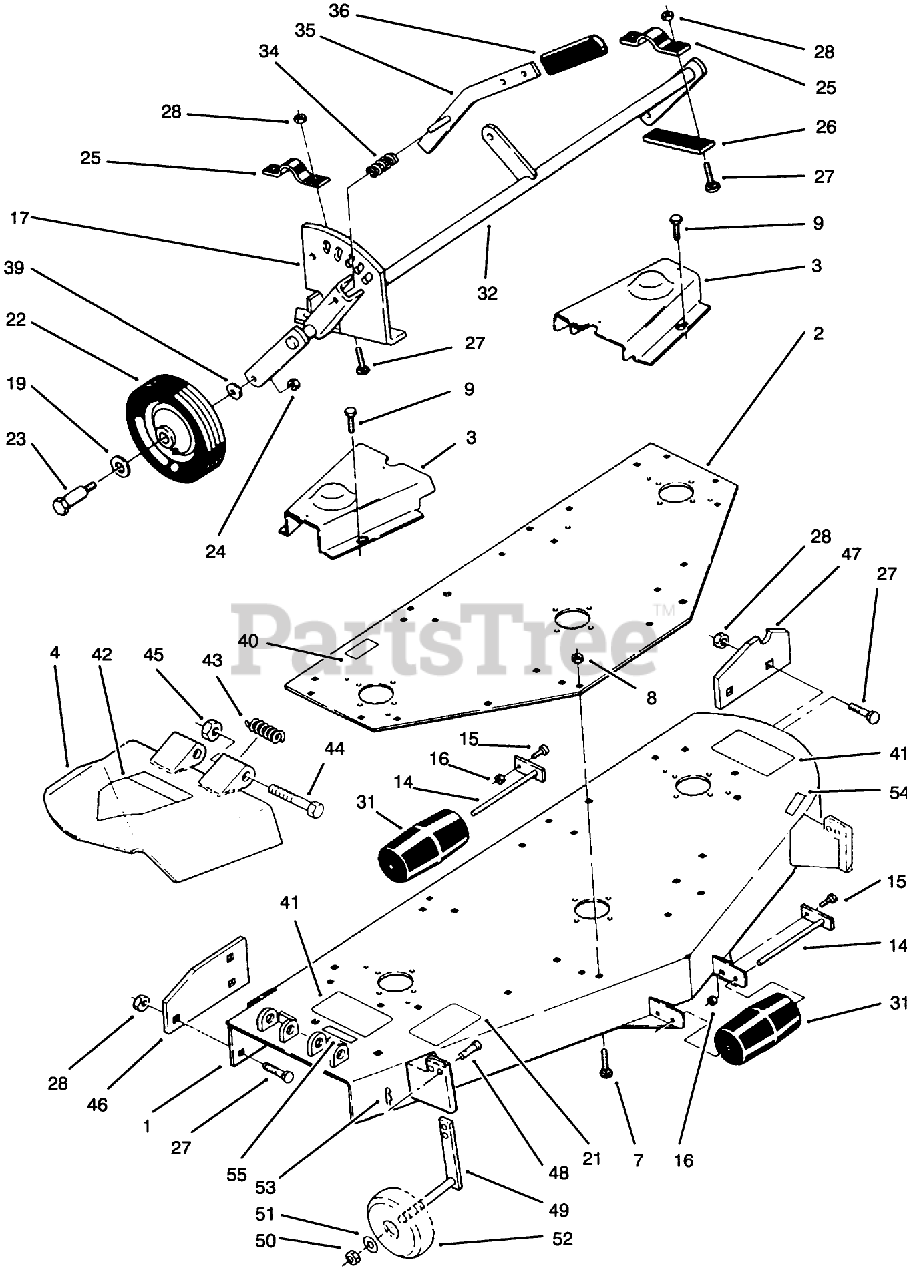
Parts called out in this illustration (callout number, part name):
1	DECK/DECAL ASM-SERVICE
2	PLATE-TOP REINFOR *R
7	BOLT-CARR
8	NUT-LOCK, NI
9	SCREW-HWH, TAPTITE
14	ROLLER-SHAFT
15	BOLT-CARR
16	NUT-LOCK, NI
19	WASHER-FLAT
21	DECAL-BELT INSTALL
23	SCREW-HH
24	NUT-LOCK, NI
27	BOLT-CARR
28	NUT-LOCK, NI
31	ROLLER-ANTI SCALP
34	SPRING-COMPRESSION
39	SPACER
40	DECAL-HOC
41	DECAL-DANGER, THROWN OBJECT
43	SPRING
44	SCREW-HH
45	NUT-LOCK, NI
49	GAGE-WHEEL
50	NUT-LOCK, NI
51	WASHER-FLAT
53	PIN-HAIR
54	DECAL - WHEEL ADJUSTMENT
55	DECAL-DANGER
